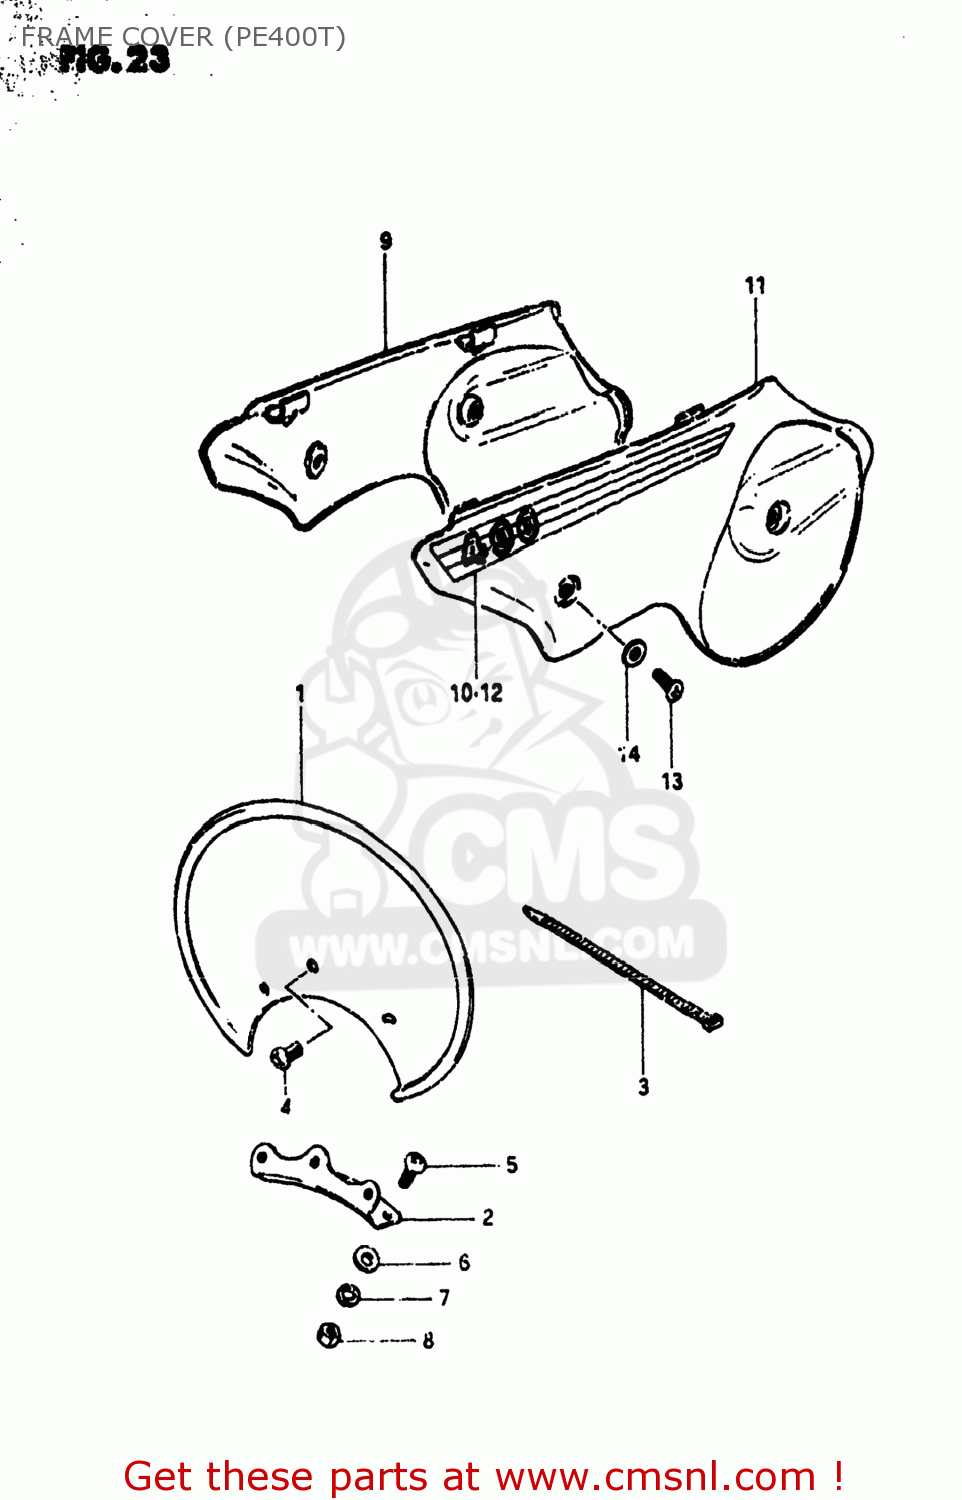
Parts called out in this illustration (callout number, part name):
1	PLATE,NUMBER,FRONT
2	BRACKET
3	CLAMP
4	SCREW
5	SCREW
6	WASHER
7	LOCK WASHER
8	NUT
9	COVER,FRAME,R(YELLOW)
10	TAPE,FRAME COVER,RIGHT
11	COVER,FRAME,L(YELLOW)
12	TAPE,FRAME COVER,LEFT
13	SCREW 6X12
14	WASHER
